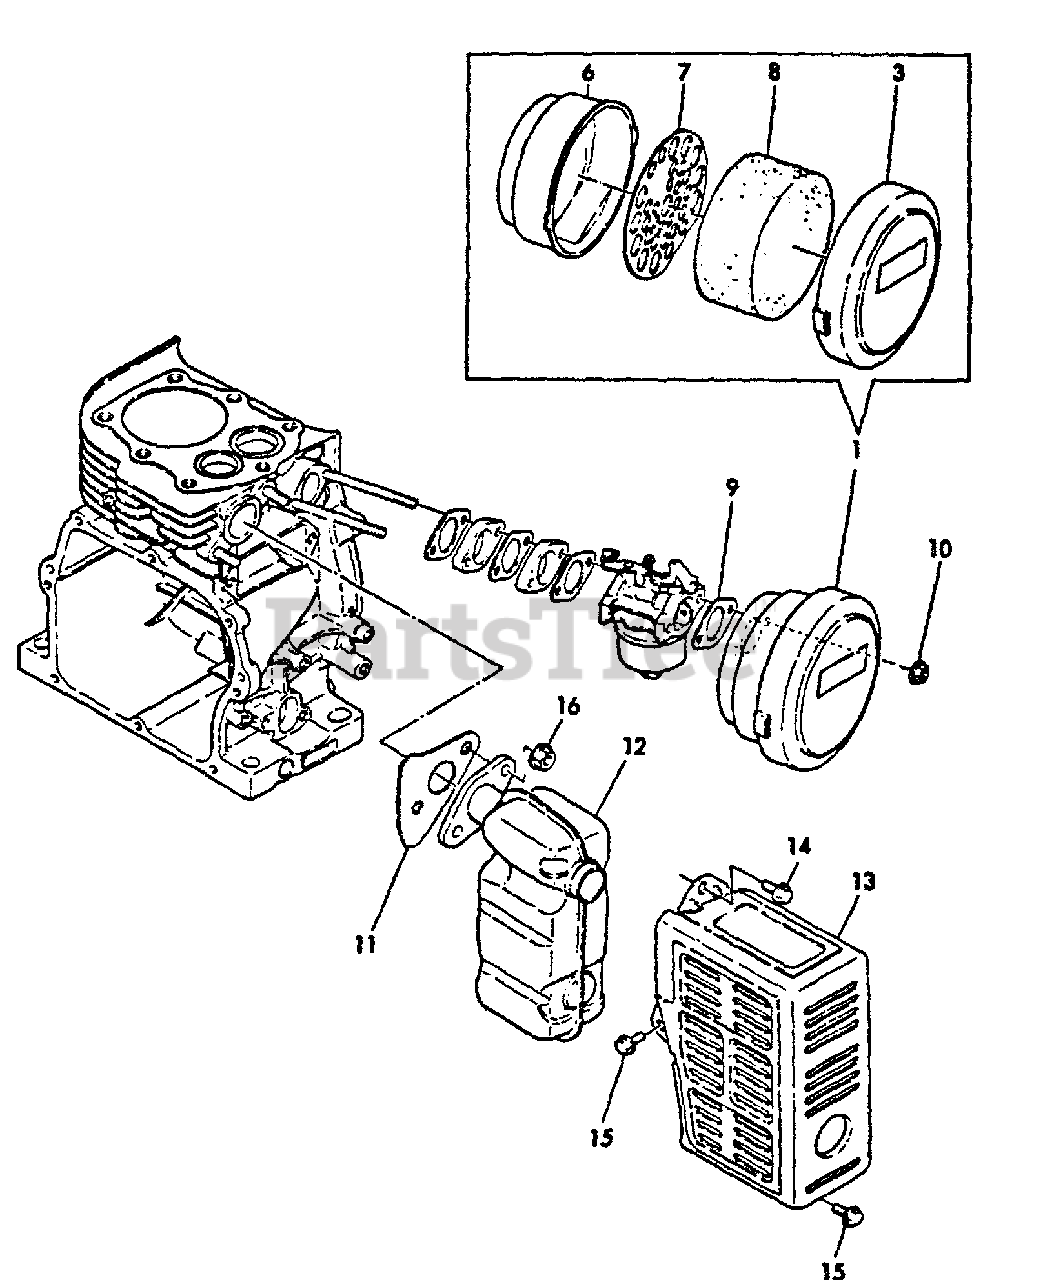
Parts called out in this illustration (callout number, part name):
1	CLEANER ASSY, AIR
3	CAP ASSY, CLEANER
6	CASE, AIR FILTER
7	PLATE, ELEMENT
8	FILTER, AIR
9	GASKET, INTAKE
10	U-NUT M6
11	GASKET, EXHAUST
13	COVER, MUFFLER
14	BOLT - 6×12 -- PLATED
15	BOLT - 6×8 -- PLATED
16	U-NUT M8
